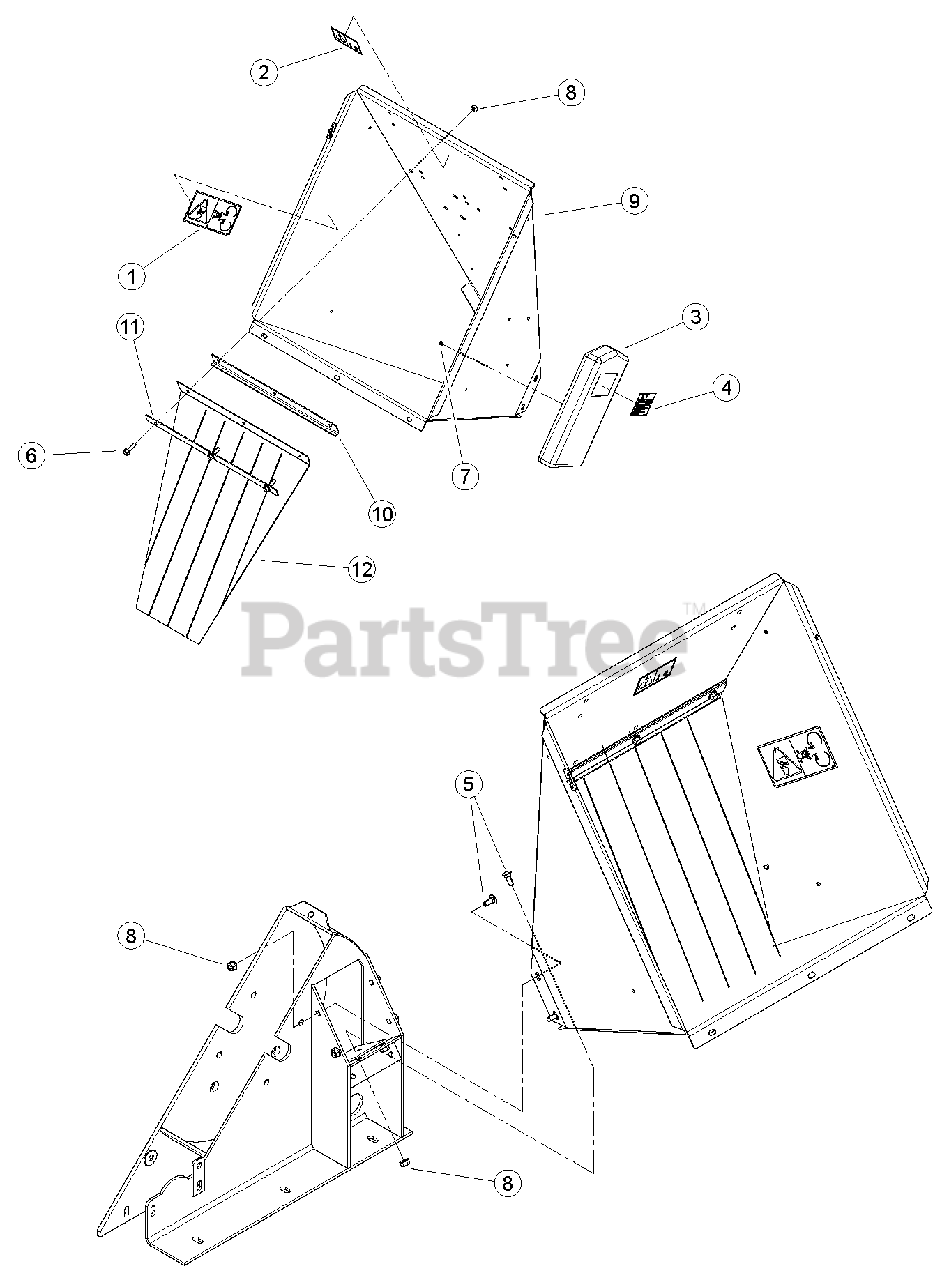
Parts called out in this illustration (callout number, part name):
1	DECAL, BLADE DANGER ISO
2	DECAL, MAINTENANCE ISO
3	CONTAINER, INSTR. MANUAL
4	DECAL, MULTILINGUAL MANUAL
5	BOLT, 3/8 X 1" GR5 CRG NC ZP
6	BOLT, 3/8 X 1-1/4 FLANGE NC
7	RIVET, 1/4X1/2 DOME HD BLIND SS
8	NUT, 3/8-16 NYLOCK FLANGE
9	WELDMENT, 5 INCH CHIPPER CHUTE
10	ANGLE, FLAP ANCHOR
11	STRIP, FLAP RETAINER
12	FLAP, CHIPPER CHUTE
